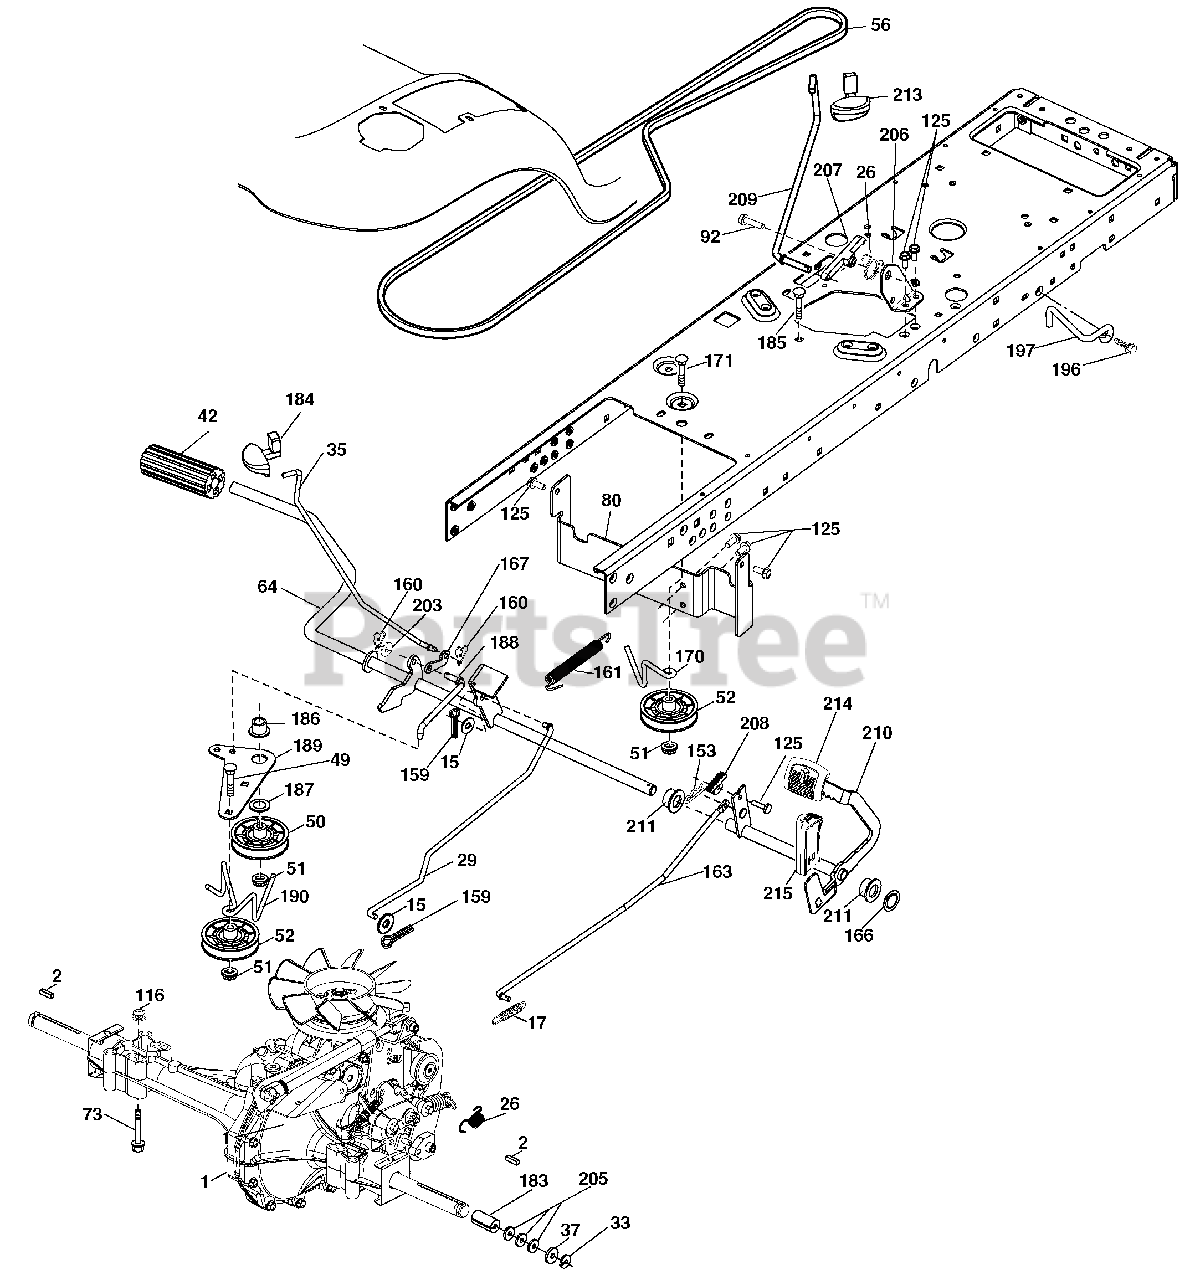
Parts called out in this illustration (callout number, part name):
2	Key
15	Washer 13/32 x 13/16 x 16 Ga.
17	Spring, Brake
29	Rod, Brake
33	Ring E
35	Rod, Brake, Park
37	Washer 25/32 x 1-1/4 x 16 Ga.
42	Cover, Foot Pedal
49	Bolt
50	Pulley Idler Flat
51	Lock Nut 3/8-16
52	Idler V-Groove 910" Offset
56	V-Belt, Drive
64	Shaft Asm. Pedal Brake Control
73	Bolt Hex Flghd 5/16-18 Gr. 5
80	Bracket Strap Torque
92	Bolt Fin Hex 5/16-18 unc x 1.25
116	Nut Lock Hex Flange 5/16-18
125	Screw 5/16-18 x 3/4
153	Retainer Spring
159	Pin Cotter 1/8 x 3/4
160	Retainer Clip
161	Spring, Return, Clutch
163	Rod Pedal Control
166	Nut Push .625
167	Latch Brake Parking
170	Keeper Belt Centerspan
171	Bolt
183	Spacer Axle
184	Handle Parking Brake
185	Bolt
186	Spacer Retainer
187	Washer
188	Link Clutch Ground Drive
189	Bellcrank Ground Drive
190	Keeper Bellcrank Ground Drive
196	Screw 3/8-16 x 1
197	Link Clutch Anti Rotation
203	Washer 11/32 x 11/16 x 16 Ga.
205	Washer 25/32 x 1-5/8 x 16 Ga.
206	Bracket Mount Latch Cruise
207	Latch Control Cruise
208	Gear Sector Control Cruise
209	Rod Control Cruise
210	Rockr Asm. Pdeal Control
211	Bearing Nylon
213	Knob control Cruise
214	Pad Pedal Forward
215	Pad Pedal Reverse
